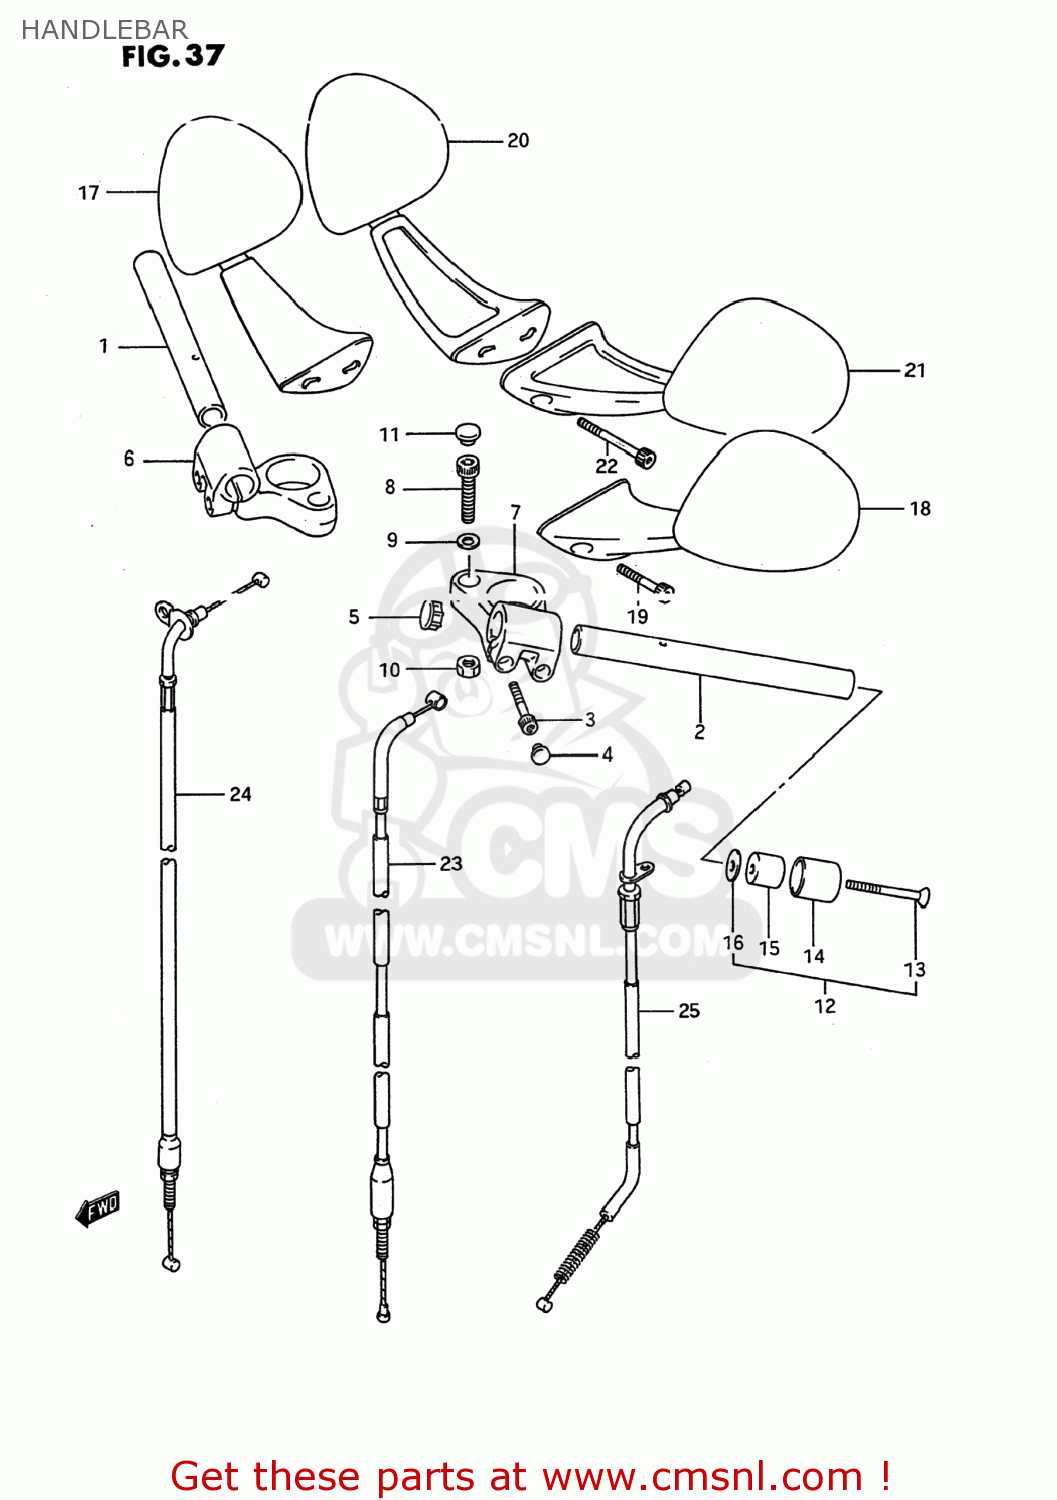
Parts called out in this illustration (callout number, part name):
1	HANDLEBAR,R
2	HANDLEBAR,L
3	BOLT
4	CAP(OD:10)
5	CAP,HANDLEBAR
6	HOLDER,HANDLEBAR,R
7	HOLDER,HANDLEBAR,LEFT
8	BOLT 10X45
9	WASHER
10	NUT
11	CAP(OD:20)
12	BALANCER SET,HANDLEBAR
13	SCREW
14	CAP,BALANCER
15	BALANCER,HANDLE
16	SPACER,BALANCER
17	MIRROR ASSEMBLY,REAR VIEW
18	MIRROR ASSEMBLY,REAR VIEW
19	BOLT
20	MIRROR ASSEMBLY,REAR VIEW
21	MIRROR ASSEMBLY,REAR VIEW
22	BOLT
23	CABLE ASSY,CLUTCH
24	CABLE ASSY,THROTTLE
25	CABLE,STARTER
